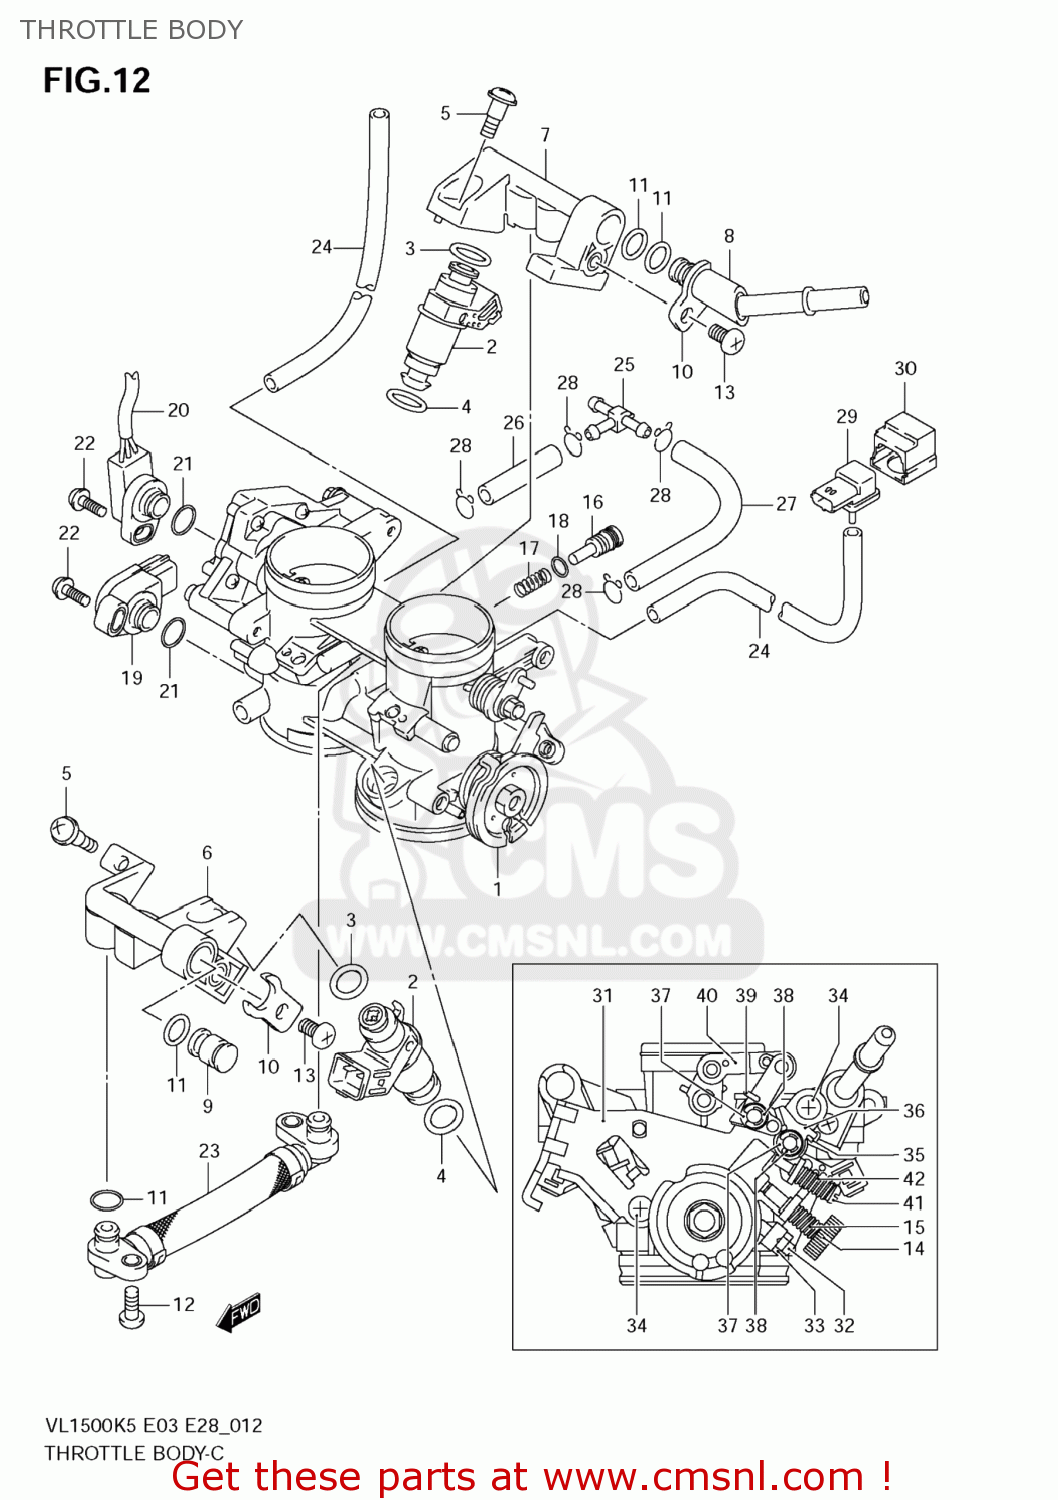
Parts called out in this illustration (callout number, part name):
1	THROTTLE BODY KIT
2	INJECTOR ASSY
3	O RING
4	O RING
5	SCREW,THROTTLE COVER
6	PIPE,FUEL
7	PIPE,FUEL
8	JOINT
9	PLUG
10	PLATE
11	O RING
12	SCREW
13	SCREW
14	SCREW,IDLE
15	SPRING
16	SCREW,ADJUST
17	SPRING
18	O RING
19	SENSOR ASSY,THROTTLE MAIN
20	SENSOR ASSY,TH
21	O RING
22	SCREW
23	PIPE ASSY,FUEL
24	HOSE
25	JOINT
26	HOSE
27	HOSE
28	CLIP
29	SENSOR,PRESSURE
30	HOLDER,SENSOR
31	PLATE,STAY
32	SCREW,STOP
33	NUT
34	SCREW
35	SPRING
36	LEVER,LINK
37	WASHER
38	E CLIP
39	SPRING
40	LEVER SET,LINK
41	SCREW
42	SPRING
